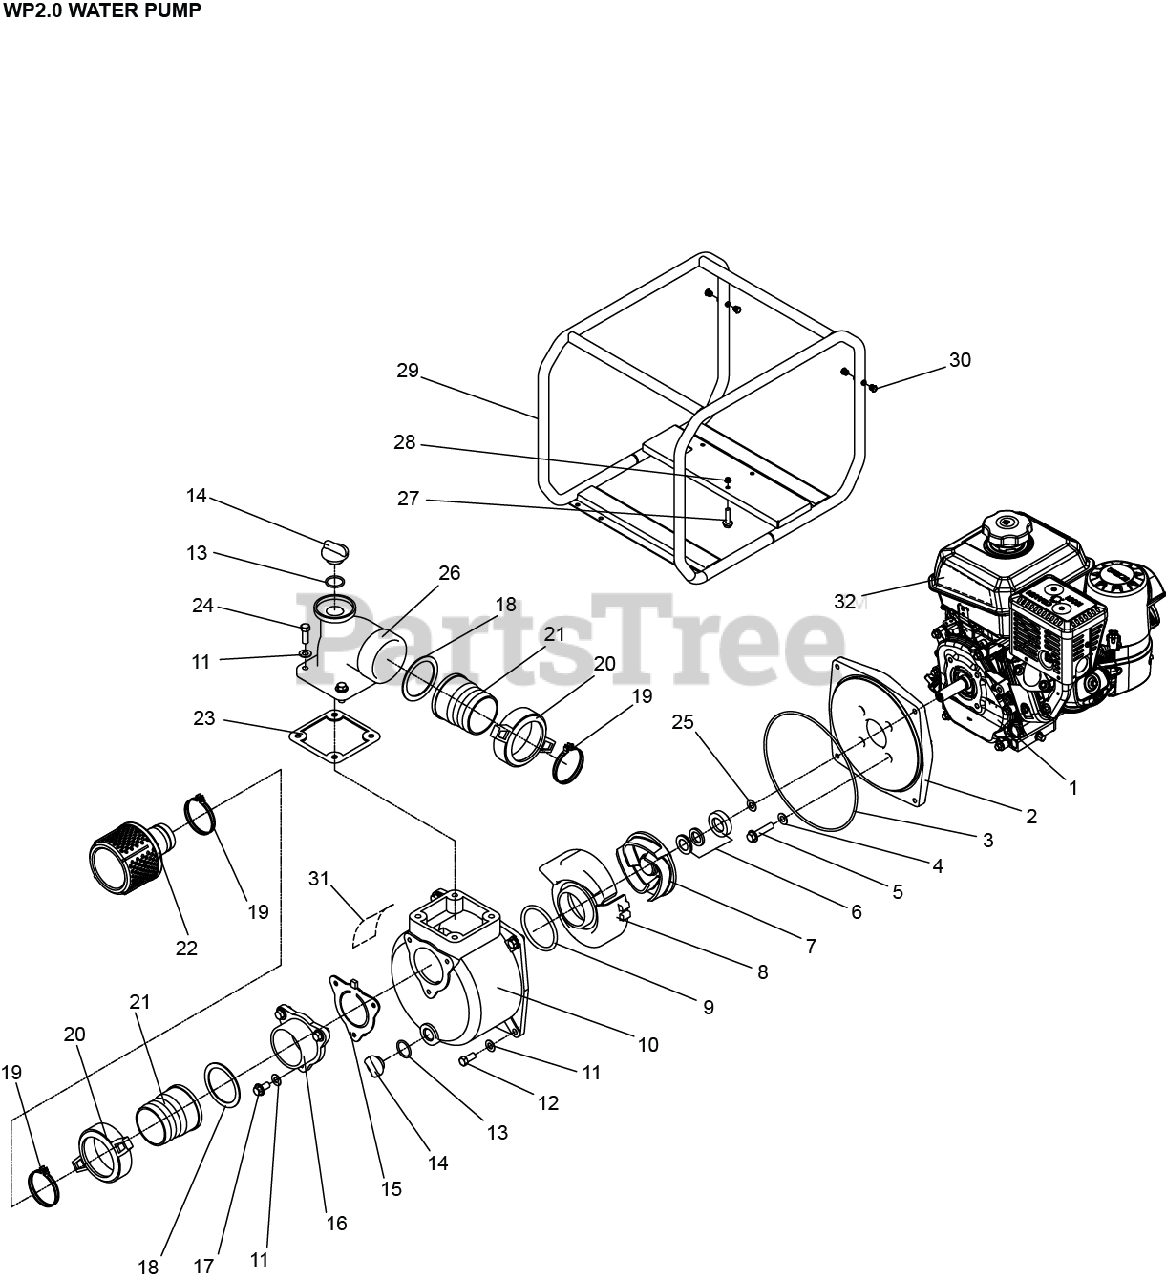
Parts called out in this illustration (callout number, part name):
1	CH270 E3 MARKETING BASIC
2	ADAPTER, PUMP COVER WP2.0
3	O-RING 196 WP2.0
4	WASHER 8 TP3.0
5	BOLT 5/16-24UNF-2A (L=60)
6	SEAL, MECHANICAL WP3.0
7	PUMP ASSEMBLY, IMPELLER WP2.0
8	HOUSING, DIFFUSOR WP2.0
9	O-RING 65 WP2.0
10	BODY, PUMP WP2.0
12	BOLT M8X22
13	O-RING 30*3.1 TP3.0
14	PLUG TP3.0
15	GASKET WP2.0
16	FLANGE, SUCTION WP2.0
17	BOLT M8X16
18	GASKET, RUBBER PACKING WP2.0
19	CLAMP WP2.0
20	NUT, JOINT GRIP WP2.0
21	FITTING, PIPE JOINT WP2.0
22	FILTER NET WP2.0
23	GASKET, RUBBER PAD WP2.0
24	BOLT M8X25
25	SHIM, ADJUSTING
26	ELBOW OUTLET SEAT WP2.0
27	BOLT M8X40 GB 5789
29	FRAME ASSEMBLY WP3.0
30	PLUG, END CAP
31	PERFORMANCE LABEL
32	BRAND LABEL
